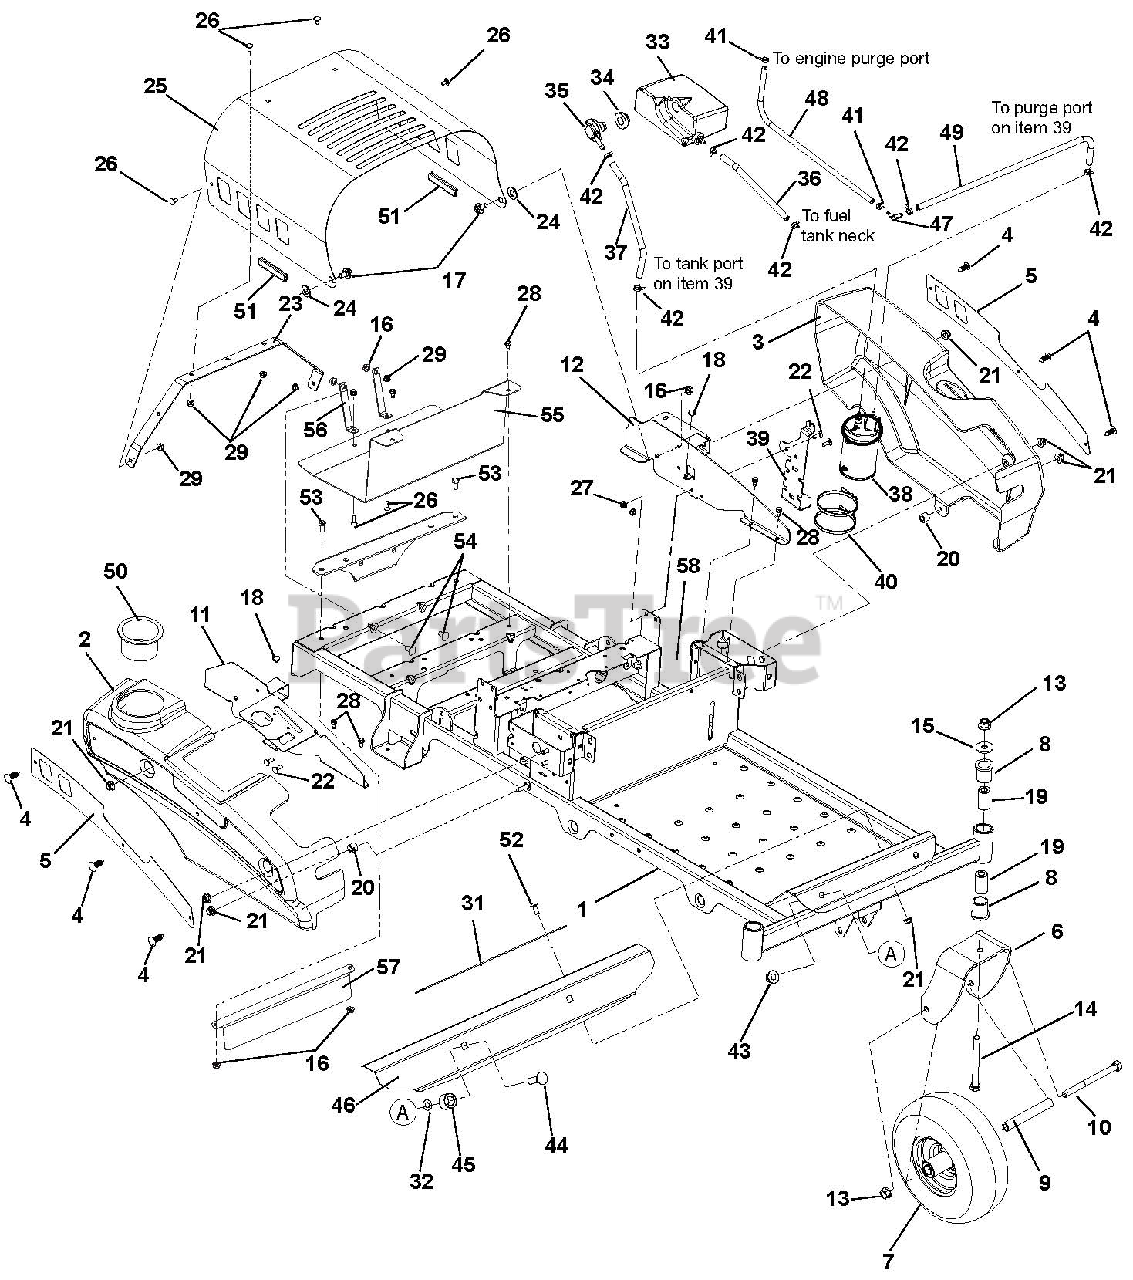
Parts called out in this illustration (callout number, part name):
1	KIT, ZOOM/ZT FRAME W/ DECALS
2	FENDER, RH
3	FENDER, LH
4	RIVET, .25 NYLON PANEL
5	PLATE, FENDER
6	WMT, CASTER FORK
7	TIRE/WHEEL ASSY, 11X4-5
8	BSHG-FLG 1.00X1.25X1.50X1.50
9	SPACER, ROLLED WHEEL
10	@BLT-HEX .50-13X6.50 GR5 YWZC
11	WLDMT, RH FENDER MOUNT
12	WLDMT, LH FENDER MOUNT
13	@NUT-LK-TOP-FLG .50-13 YWZC
14	@BLT-HEX .50-13X5.00 GR5 YWZC
15	WSHR-FL-STL.511X1.441X.125 YWZ
16	@NUT-LK-TOP-FLG .38-16 YWZC
17	BOLT-SHLDR .375-16X.150
18	BUMPER GROMMET
19	SPACER, CASTER .50X1.00X1.84
20	BSHG-SLV .391X.688X.52 PM
21	@NUT-LK-NYL-FLG .31-18 YWZC
22	@BLT-RDHDSQNK .25-20X.75 G5YZ
23	BRACE, HOOD
24	WSHR-FL-NYL .518X1.000X.080
25	HOOD, ZOOM
26	@BLT-RDHDSQNK .25-20X.50 G5YZ
27	@NUT-LK-NYL-FLG .25-20 YWZC
28	SCR-TAP .25-20X.50 HWH TR YWZ
29	@NUT-LK-TOP-FLG .25-20 YWZC
30	@NUT-LK-TOP-FLG .25-20 YWZC
31	GRIP, ADHESIVE (1" X 16" BLK)
32	NUT-PUSH, .50
33	EXPANSION TANK SUB ASSY
34	GROMMET, REMOTE VENT NITRILE
35	VALVE, COMBINATION
36	HOSE, .25 LOW-PERM BULK GAS
37	HOSE, .25 LOW-PERM BULK GAS
38	CARBON CANISTER, 300CC
39	BRKT-MOUNT, CANISTER BBZ
40	P-PLASTIC TIE STRAP LARGE
41	CLAMP-HOSE, SPRING .188
42	CLAMP, FUEL LINE
43	@NUT-LK-NYL-FLG .50-13 YWZC
44	@BLT-RDHDSQNK .50-13X1.75 G5YZ
45	TUBE, UPPER CONTROL PIVOT
46	FOOTREST
47	FITTING-3/16X1/4 90DEGREE VAC
48	HOSE, .188 LOW-PERM BULK GAS
49	HOSE, .25 LOW-PERM BULK GAS
50	CUPHOLDER, SNAP-IN 3.75OD
51	EDGING, CLUTCH PADDLE - 2.00"
52	BLT-RDHDSQNK .50-13X7.00
53	@BLT-HEX .38-16X1.00 GR5 YWZC
54	@BLT-RDHDSQNK .38-16X1.00 G5YZ
55	GUARD, HEAT SHIELD (ZOOM/ZT)
56	STRAP, HEAT SHIELD (ZOOM/ZT)
57	GUARD, HOT SURFACE (ZOOM/ZT)
58	GROMMET 1.0ID X 1.38 OD
